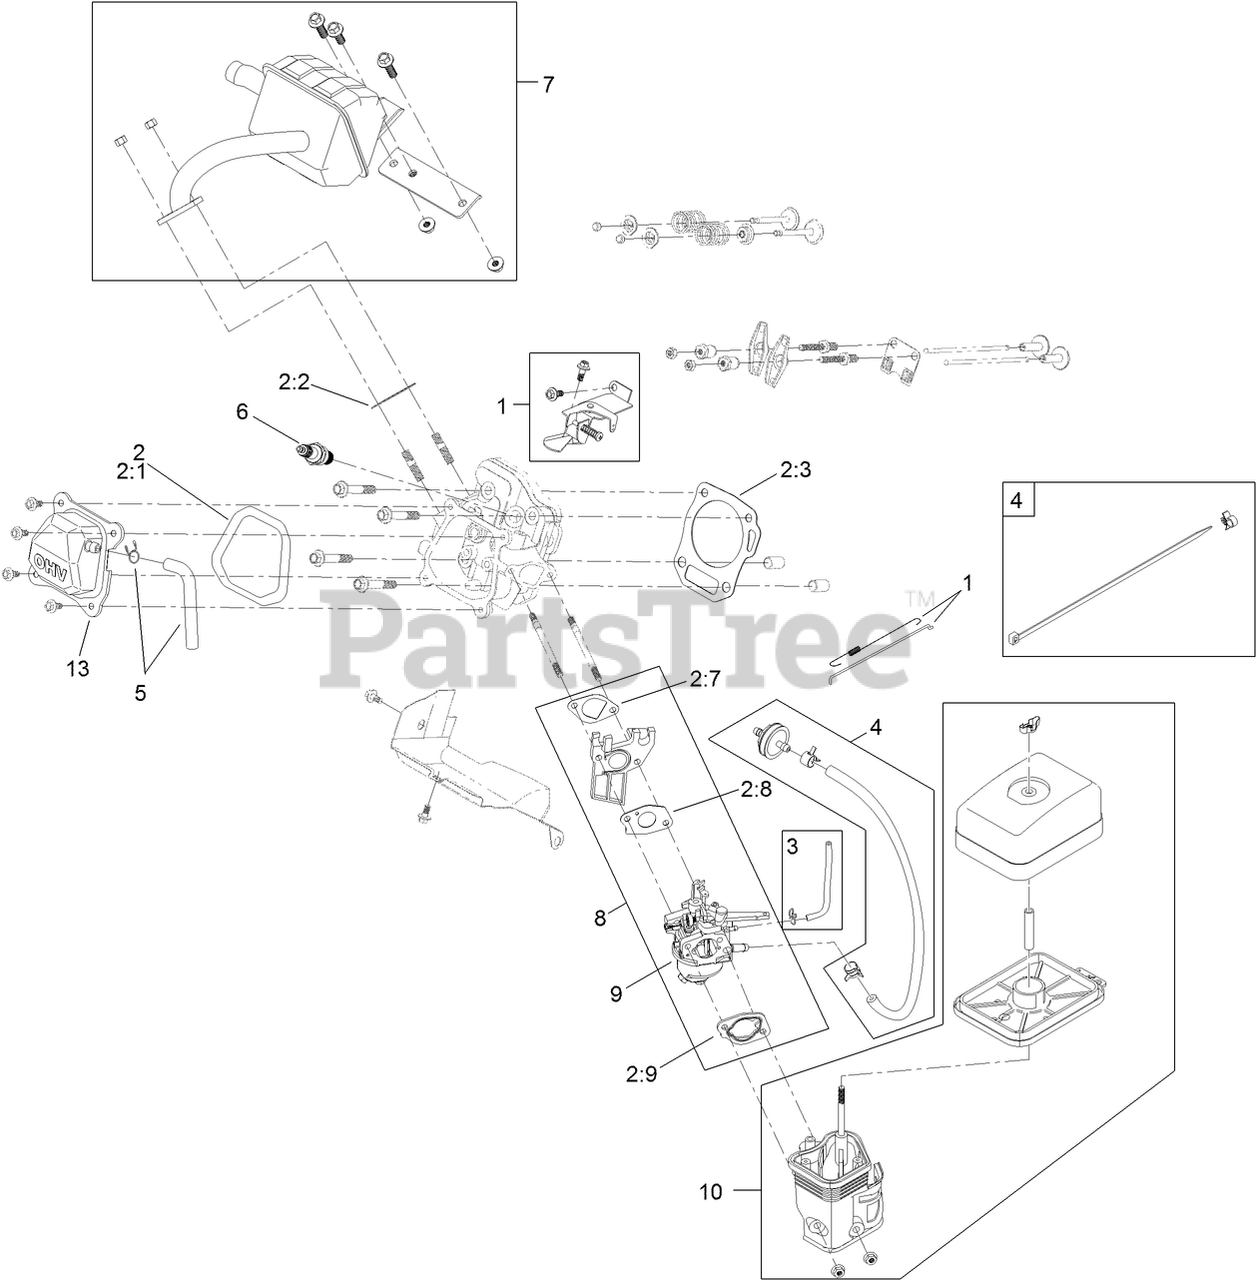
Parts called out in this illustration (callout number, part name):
1	GOVERNOR KIT
2	GASKET AND SEAL KIT
2:1	GASKET-COVER, VALVE
2:2	Gasket-Exhaust
2:3	GASKET-HEAD, CYLINDER
2:4	Loose Parts Package
2:5	Loose Parts Package
2:6	GASKET-COVER, CRANKCASE
2:7	GASKET-CARBURETOR
2:8	GASKET-CARBURETOR
2:9	GASKET-CARBURETOR
4	FUEL LINE KIT
5	BREATHER TUBE KIT
7	MUFFLER KIT
8	CARBURETOR KIT
9	CARB REPAIR KIT WITH GASKETS
10	HEATER BOX KIT
13	VALVE COVER ASM
